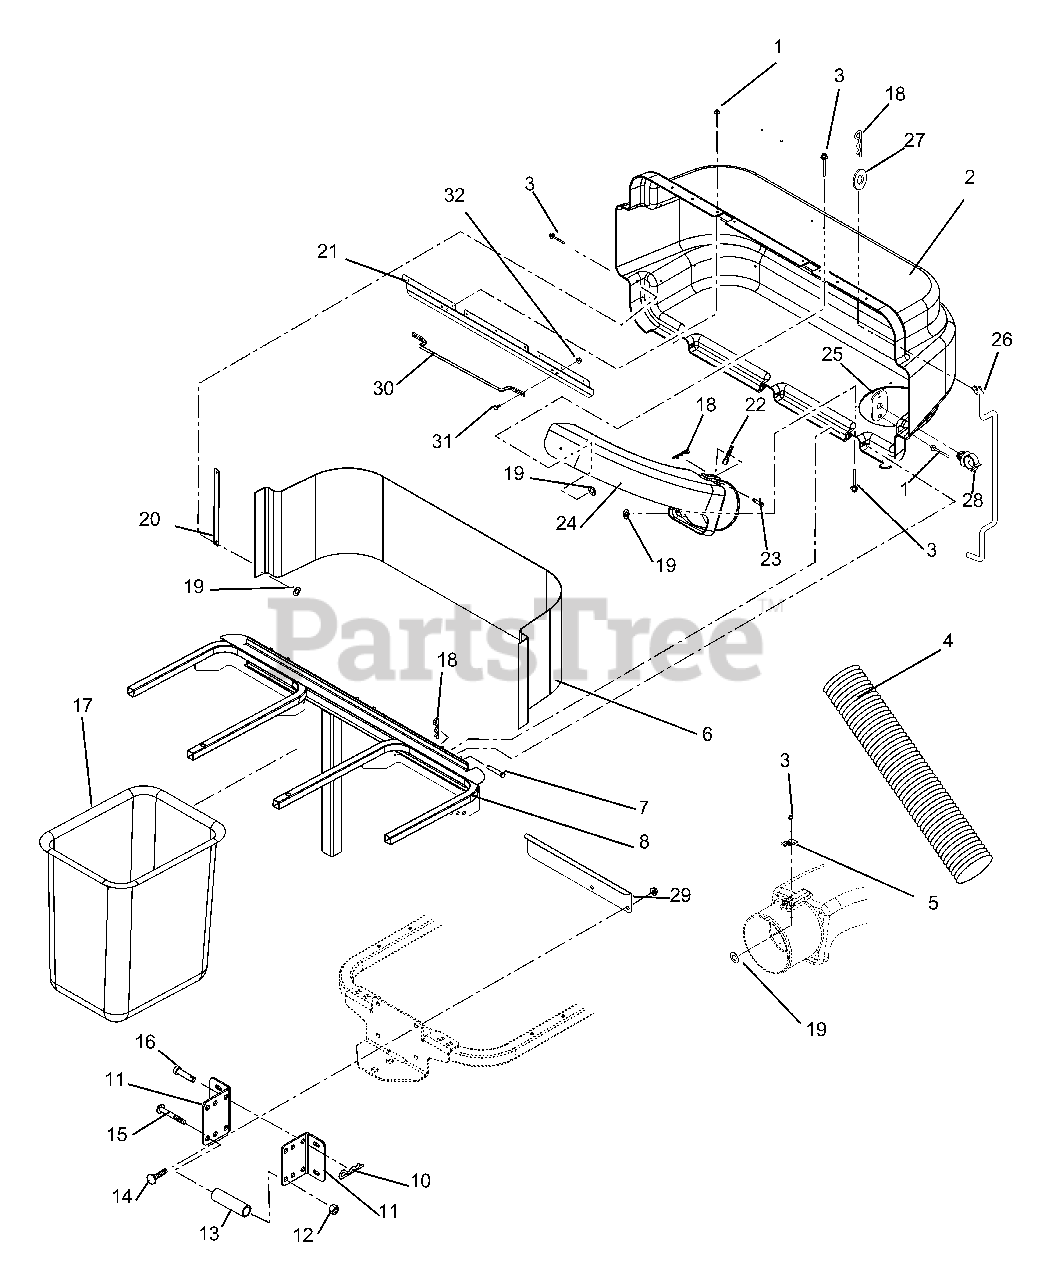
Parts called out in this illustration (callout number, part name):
1	Rivet-Pop .187 x .402
2	Cover, Bagger with Decal
3	Rivet-Pop .187 x .375
4	Hose 7 x 45
5	Thumb Latch
6	Screen, Bagger
7	Pin-Clevis .368/.373 x 3.25
8	Weldment, Bagger Frame
9	Nut-Locking-Top-Flange .38-16
10	Pin-Hair-External .12 x .31 x 2.37
11	Bracket, Bagger Mount
12	Nut-Locking-Top-Flange .50-13
13	Spacer, Pivot
14	Bolt-Round Head Square Neck .38-16 x 1.25 Grade 5
15	Bolt-Hex .50-13 x 3.00 Grade 5
16	Pin-Clevis .494 x 2.50
17	Grass Bagger Basket
18	Pin-Hair
19	Washer-Flat-Steel .219 x .50 x .049
20	Strap, Cover
21	Latch, Cover
22	Indicator, Flow
23	Pin-Clevis .31 x 2.62 Grade 5
24	Boot, Upper
25	Plate, Rod Clip
26	Prop-Rod, Bagger
27	Washer-Flat-Steel .046 x .812 x .065
28	Clip .38
29	Deflector, Exhaust
30	Bagger Handle
31	Bolt, Round Head Square Neck .25-20 x .75 Grade 5
32	Nut, Locking Top Flange .25-20
